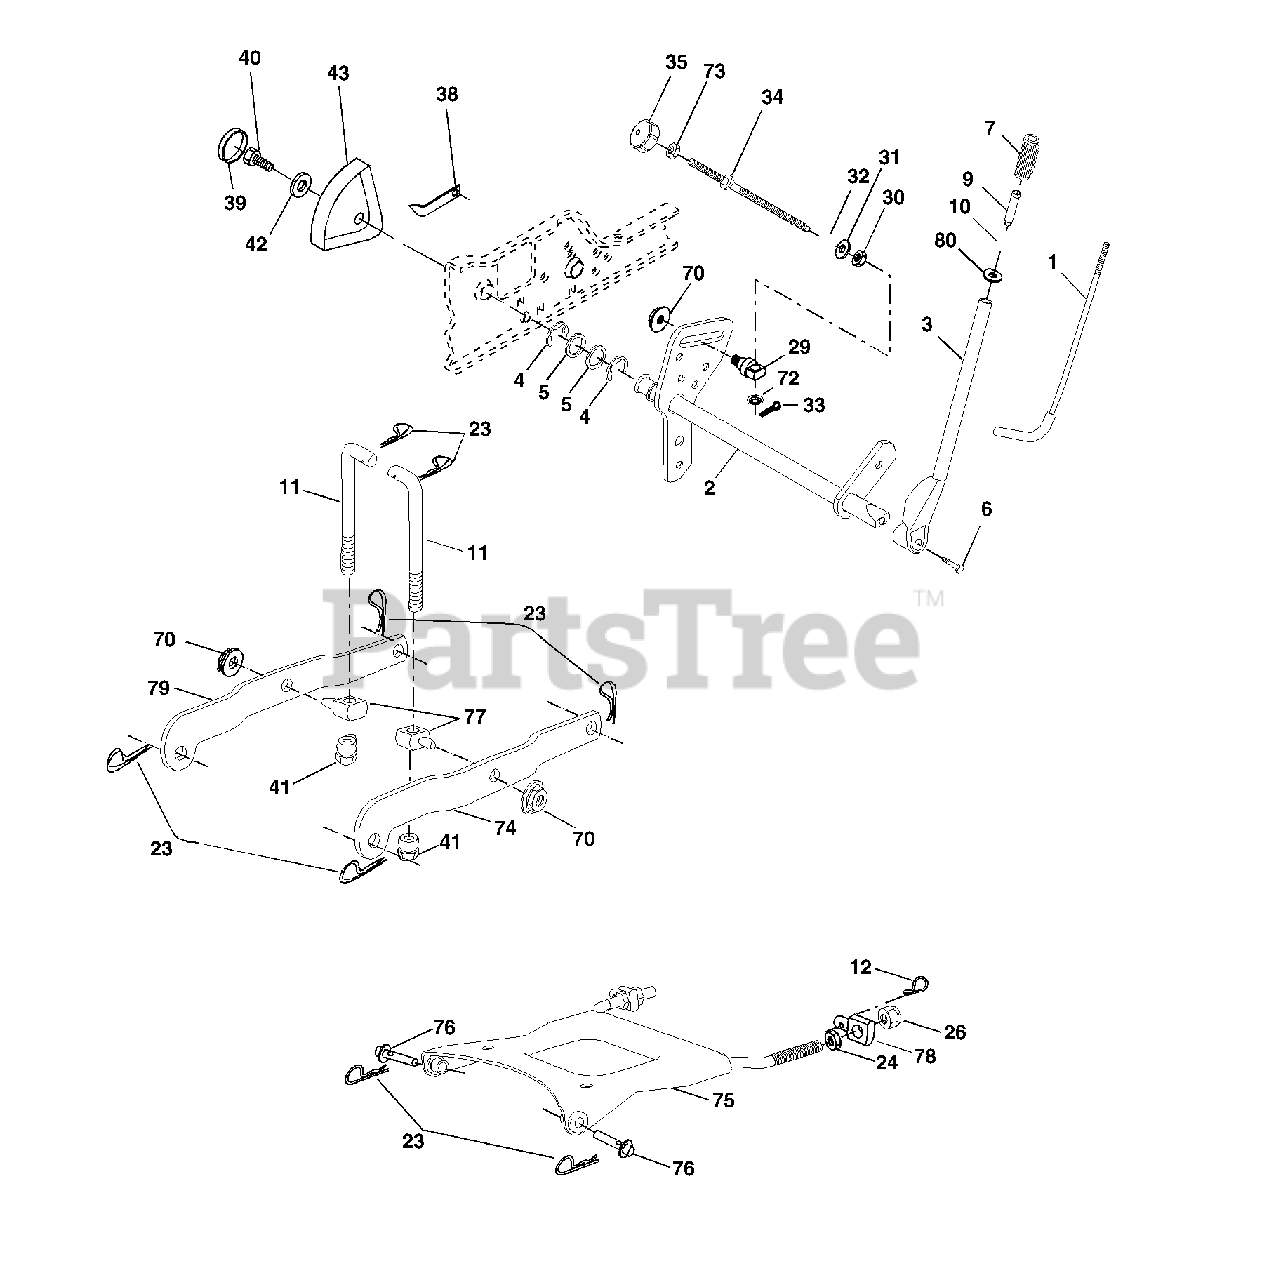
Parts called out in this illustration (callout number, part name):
1	Rod Asm., Lever
2	Shaft Asm., Lift Vgt
3	Lever Asm., Lift Rh
4	E-Ring Truarc #5133-87
5	Washer 29/32 x 1-1/4 x 16 Ga.
6	Bolt, Fin Hex 3/8-16 x 1-1/2
7	Grip, Handle Fluted
8	Button, Plunger
9	Plunger, Lever Lift
10	Spring 2-1/8"
11	Link Lift
12	Retainer, Spring
13	Arm Susp. Rear LH
23	Retainer, Spring
24	Nut, Jam Hex 1/2-13 Unc
26	Nut, Crownlock 1/2-13 Unc
29	Trunnion Inf. Height
30	Nut, Special
31	Washer 13/32 x 5/8 x 16 Ga.
32	Spring, Compression Inf Hgt
33	Pin, Cotter 3/32 x 1/2
34	Rod, Adj Lift
35	Knob, Inf 3/8-16 Unc
38	Pointer, Height Indicator
39	Plug, Hole
40	Screw 5/16-18 x 3/4
41	Nut, Lift Link 7/16-20
42	Washer 11/32 x 1-1/2 x 10 Ga.
43	Scale, Indicator Height
70	Nut, Hexflange Lock
72	Nut, Push Phos & Oil
73	Nut Hex Jam 3/8-16 Unc
74	Arm Susp. Rear RH
75	Plate Asm Susp. Front
76	Pin Flange
77	Trunnion Susp. Arm
78	Trunnion Susp. Front
80	Washer Shim 1/4 x 5/8 x .062
